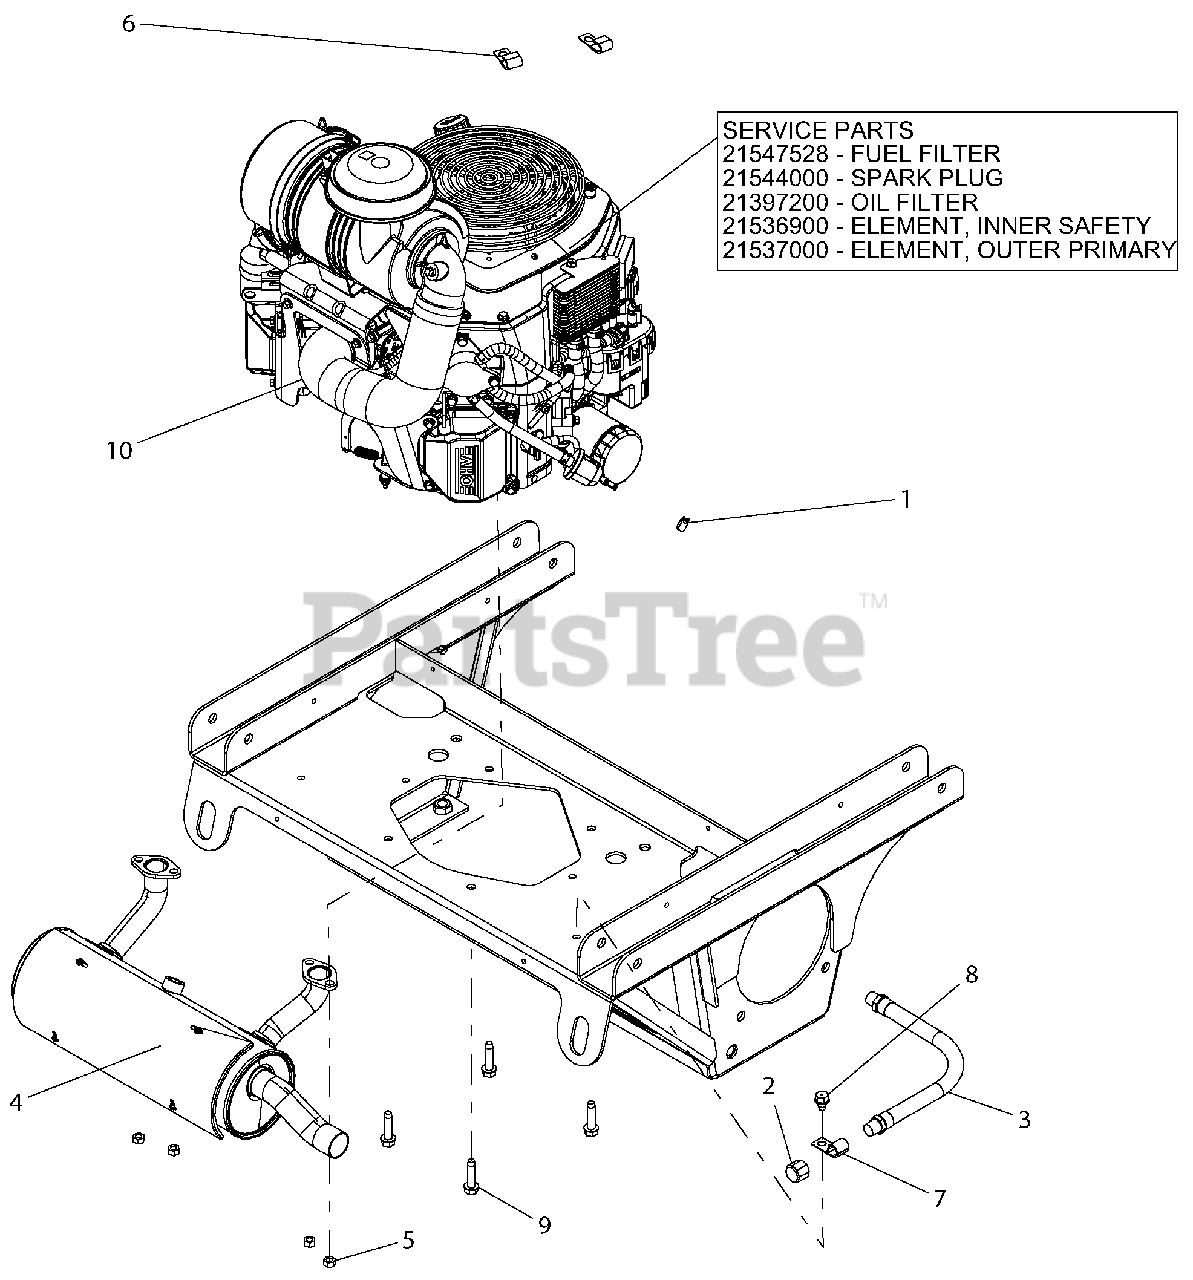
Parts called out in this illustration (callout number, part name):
1	CLAMP, FUEL LINE
2	PIPE, CAP 3/8 NPT FEMALE
3	HOSE, HYD .38-11-OK M6N0-M6N0
4	MUFFLER, KOHLER EFI
5	NUT-LK-TOP M8-1.25 YWZC
6	CLAMP, J
8	SCR-TAP .38-16X.50 HWH TR YWZ
9	SCR-TAP .38-16X1.50 HWH TR YZ
10	ENGINE, KOHLER EFI ECV749
